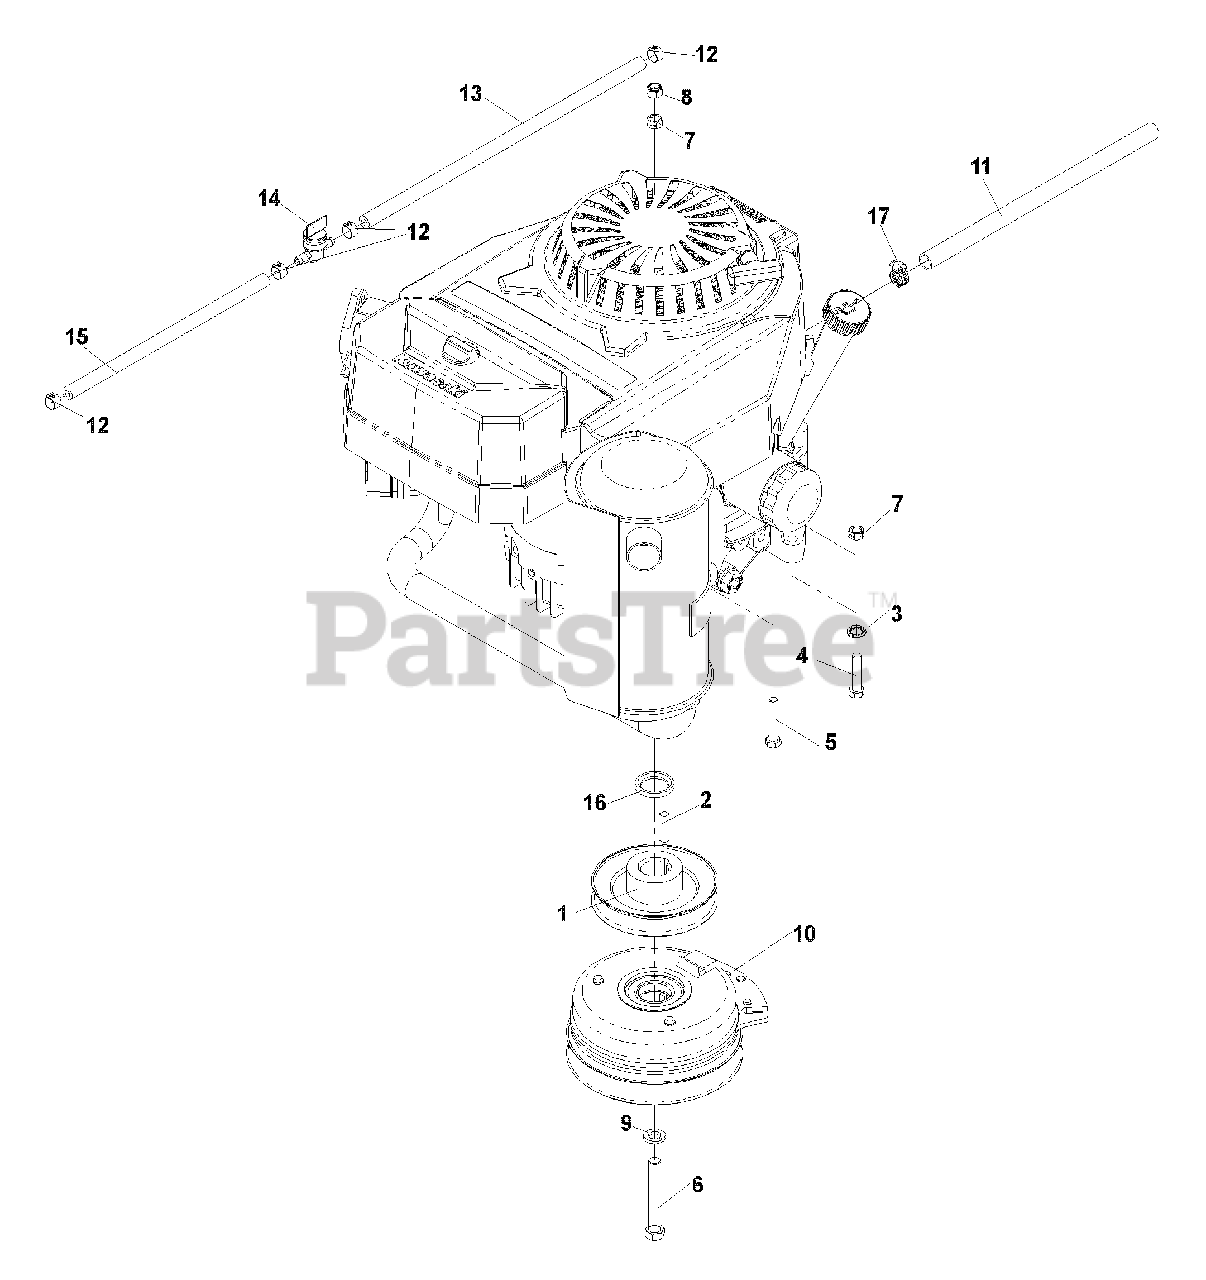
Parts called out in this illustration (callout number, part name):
2	KEY, 1/4" SQ. X 1 1/8"
3	WASHER, 3/8 INTERNAL TOOTH
4	HCS, 5/16-18 X 1 1/2, GR5
5	HCS, 5/16-18 X 1 3/4, GR5
6	HCS, 7/16-20 X 3, GR5
7	NUT, 5/16C, CENTER LOCK
8	NUT, 5/16C, NYLOC
9	LOCKWASHER, 7/16
10	CLUTCH, 125 FT/LB
11	HOSE, OIL DRAIN
12	CLAMP, HOSE
13	FUEL LINE, 14"
14	FUEL VALVE
15	FUEL LINE, 10"
17	CLAMP, HOSE, 5/16-7/8
